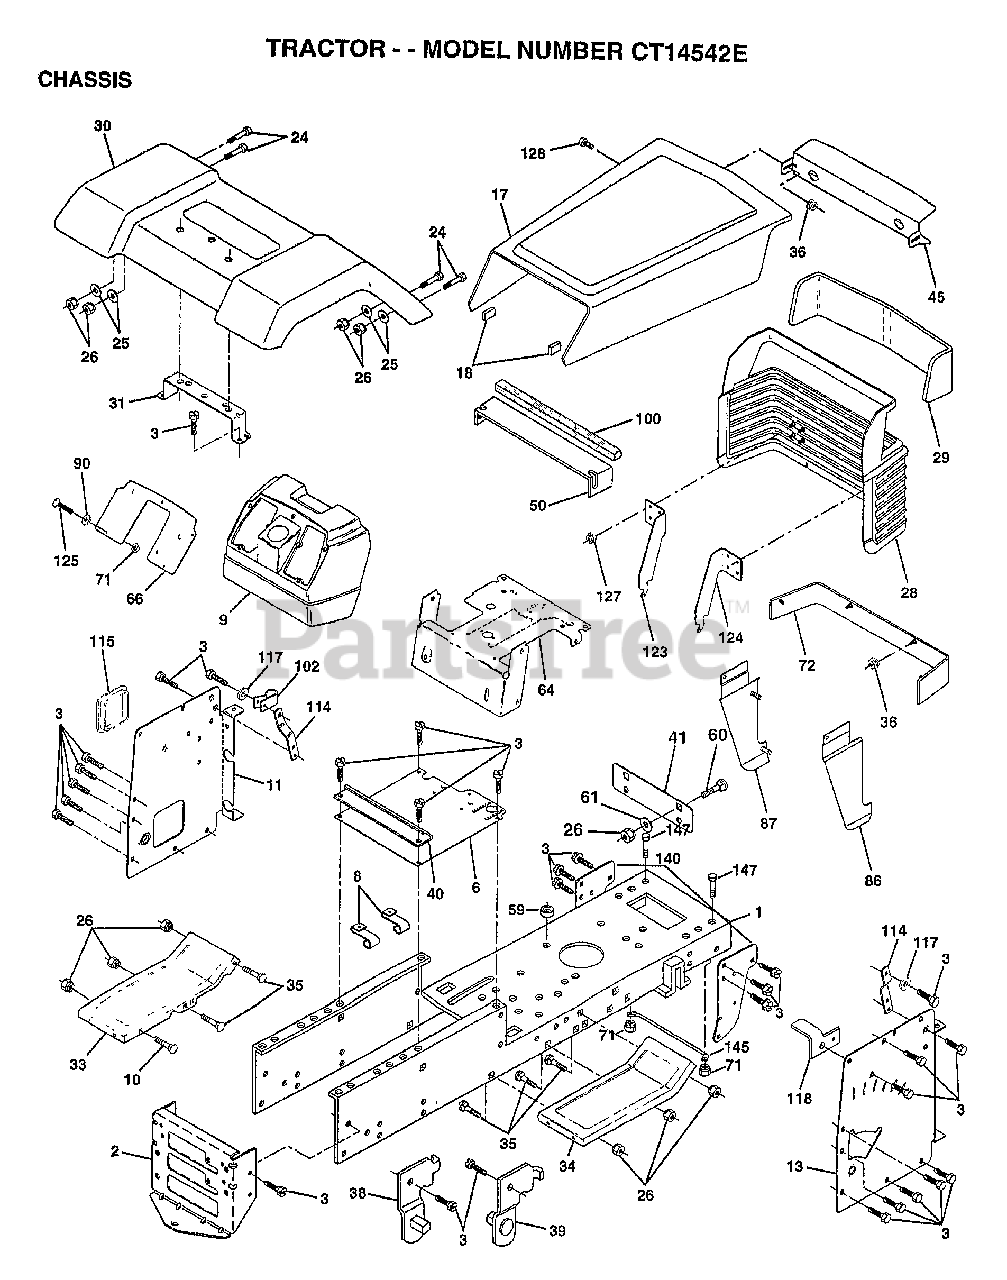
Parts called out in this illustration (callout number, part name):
1	CHASSIS ASM
3	SCREW
6	SADDLE
8	"CLIP,INSULATOR"
9	DASH.PLASTIC.BLK
11	PANEL.DASH.LH.
13	PANEL.DASH.RH.
17	HOOD/GRILLE ASM
24	BOLT
25	WASHER
26	NUT
28	GRILLE ASM WELD
30	FENDER
31	BRACKET SUPT FEND
33	FOOTREST.LH.PERF.
34	FOOTREST.RH.PERF.
35	BOLT
36	PAL NUT LT
38	BRACKET ASM LH
39	BRACKET ASM RH
40	SPACER FENDER LT
50	"BAFFLE,HOOD"
64	DASH.LOWER.LT
66	PLATE SLKSCR.OM
72	STRAP FENDER ASM
86	PANEL SIDE RH ASM
87	PANEL SIDE LH ASM
90	WASHER PM
100	FOAM STRIP T
102	CLIP T
114	BRACKET.SUPT.DASH
115	COVER ACCESS
117	WASHER.SERRATED.
118	BRACKET.CLUTCH.MC
123	BRACKET.PICK.LH.
124	BRACKET.PICK.RH.
125	SCREW
127	PAL NUT
128	SCREW SPECIAL
140	BRKT SUSPENSION
145	"ROD POVOT,CHASSIS"
147	BOLT LT
